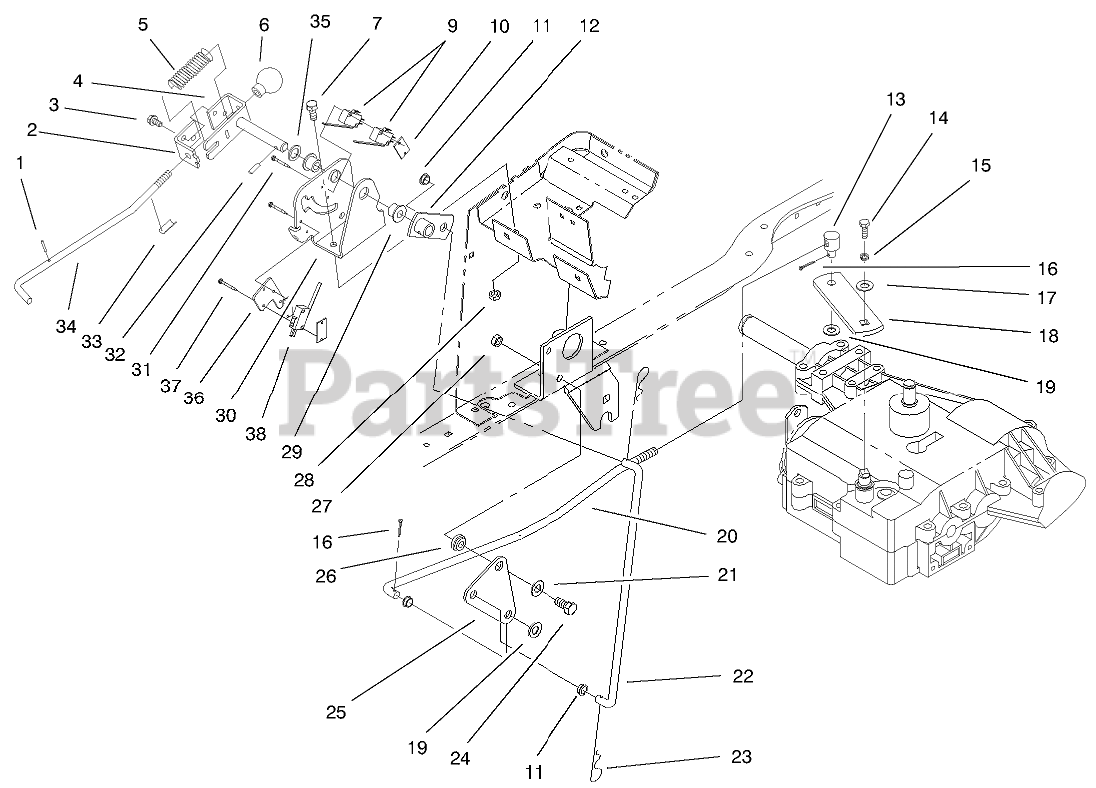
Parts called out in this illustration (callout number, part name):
2	BRACKET - SHAFT
3	SCREW-HWH
4	ARM-PIVOT
5	SPRING-COMPRESSION
7	SCREW-HH
9	SWITCH - CLUTCH
10	NUT-SPEED
11	BRG - SHIFT LINKAGE
12	TUBE-LINKAGE
13	TRUNNION
14	SCREW-HH
15	WASHER-LOCK
16	PIN-COTTER
17	SPACER
18	BRK-TRASXL SHI
19	WASHER-FLAT
20	ROD - TRANSAXLE SHIFT
21	WASHER-FLAT
22	ROD - LINKAGE
23	PIN-COTTER
24	SCREW-HH
25	BRACKET - PIVOT
26	BUSHING
27	NUT-LOCK, NI
28	NUT-LOCK, NI
29	BUSHING
30	BRKT-PIVOT MTG
31	SCREW-HH
32	PIN-ROLL, SLOTTED
33	DECAL - REVERSE GEAR
34	ROD - SHIFT
35	WASHER
36	Bracket-Switch, Nmir
37	SCREW-HH
38	SWITCH-MICRO
